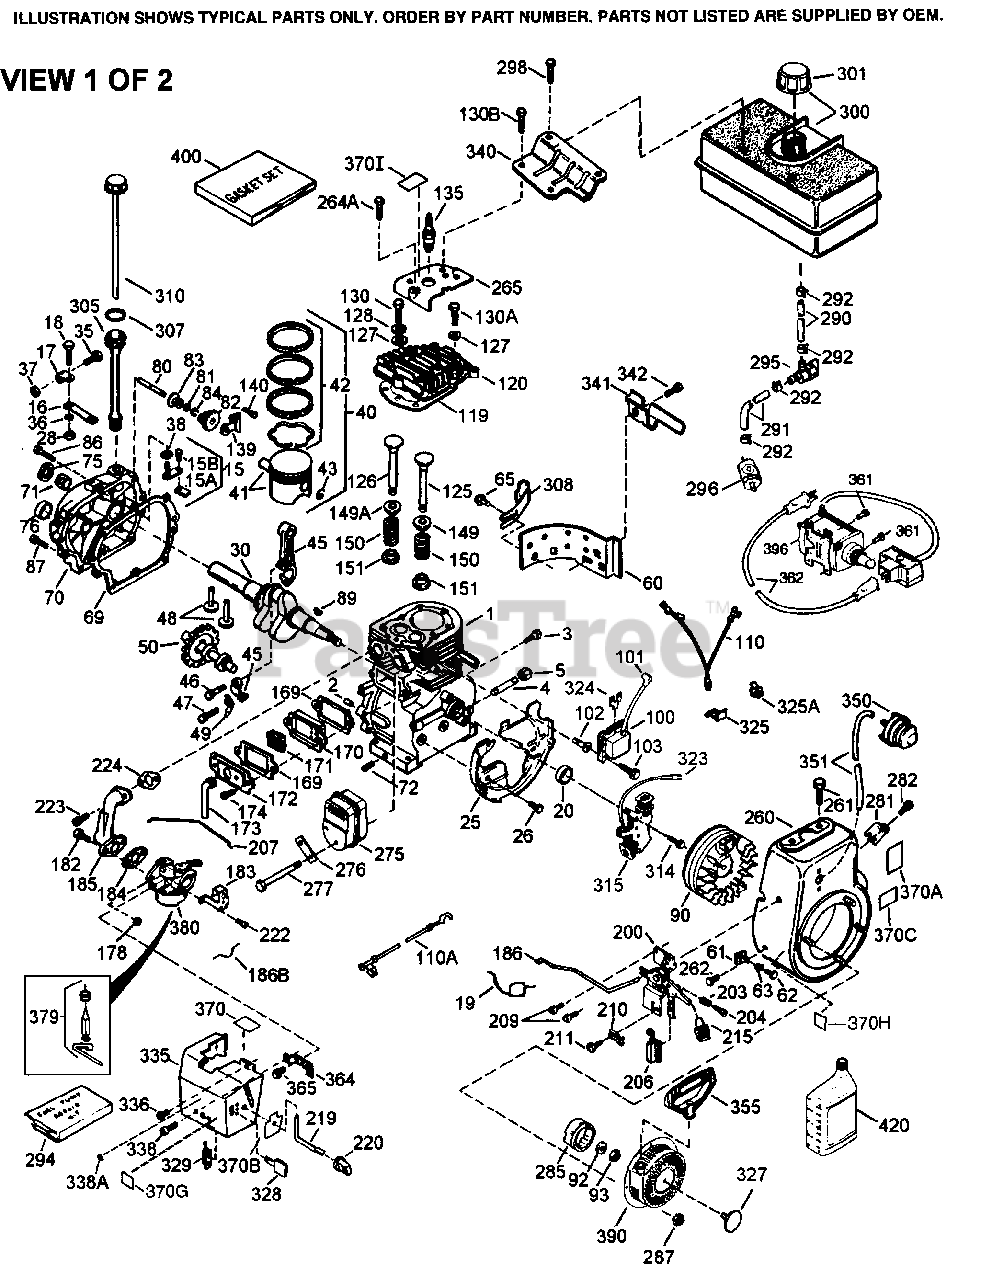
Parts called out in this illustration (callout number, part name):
1	"Cylinder (Cast Iron Liner)(3-5/16") I ncl. 2, 20, 72, 72A & 72B
2	Dowel Pin
3	Screw, 1/4-20 x 1/2"
4	Oil Drain Extension
5	Extension Cap
15	Governor Rod (Incl. 15A & 15B)
15A	Governor Yoke
15B	Screw, 6-40 x 5/16"
16	Governor Lever
17	Governor Lever Clamp
18	Screw, Torx T-15, 8-32 x 3/8"
19	Speed Control Spring
20	Oil Seal
25	Blower Housing Baffle
26	Screw, 1/4-20 x 5/8"
28	Lock Nut, 8-32
30	Crankshaft
35	Screw, 10-32 x 3/4"
36	Lock Washer #8
37	Lock Nut, 10-32
38	Retaining Ring
40	Piston, Pin & Ring Set (Std) (Incl. 4 1, 42 & 43)
40	Piston, Pin & Ring Set (.010" OS) (In cl. 41, 42 & 43)
40	Piston, Pin & Ring Set (.020" OS) (In cl. 41, 42 & 43)
41	Piston & Pin Assembly (Std) (Incl. 43 )
41	Piston & Pin Ass'y. (.010" OS) (Incl. 43)
41	Piston & Pin Ass'y. (.020" OS) (Incl. 43)
42	Ring Set (Std.) (3-5/16")
42	Ring Set (.010" OS)
42	Ring Set (.020" OS)
43	Piston Pin Retaining Ring
45	Connecting Rod Ass'y. (Incl. 47 & 49)
47	Connecting Rod Bolt
48	Valve Lifter
49	Oil Dipper
50	Camshaft (MCR)
60	Blower Housing Extension
62	Screw, 8-32 x 3/8"
69	* Cylinder Cover Gasket
70	Cylinder Cover (Incl. 71, 75 & 80)
71	Crankshaft Bushing
80	Governor Shaft
82	Governor Gear Ass'y. (Incl. 81)
83	Governor Spool
84	Retaining Ring
86	Screw, 1/4-20 x 1-3/16"
87	Screw, 1/4-20 x 1-11/16"
89	Flywheel Key
90	Flywheel (W/Ring Gear)
92	Lock Washer
93	Flywheel Nut
100	Solid State Ignition
101	Spark Plug Cover
102	Soild State Mounting Stud
103	Screw, Torx T-15, 10-24 x 15/16"
110	Ground Wire
110A	Ground Wire (10.50" with male & femal e flag terminals)
119	* Cylinder Head Gasket
120	Cylinder Head
125	Exhaust Valve (Std.)(Incl. 151)
125	Exhaust Valve (1/32" OS) (Incl. 151)
126	Intake Valve (Std.) (Incl. 151)
126	Intake Valve (1/32" OS) (Incl. 151)
128	Belleville Washer
130	Screw, 5/16-18 x 1-1/2"
130A	Screw, 5/16-18 x 1-3/4"
130C	Screw, 5/16-18 x 2"
130C	Screw, 5/16-18 x 5/8"
135	Resistor Spark Plug (RJ19LM) also ava ilable in Packaged Part #740081
139	Governor Gear Bracket
140	Screw, 10-24 x 1/2"
149	Valve Spring Cap
149A	Valve Spring Cap
150	Valve Spring
151	Valve Spring Keeper
169	* Valve Cover Gasket
170	Breather Body
171	Breather Element
172	Valve Cover
173	Breather Tube
174	Screw, 10-24 x 1/2"
178	Nut & Lock Washer 1/4-28
182	Screw, 1/4-28 x 1"
183	Choke Bracket
184	* Carburetor To Intake Pipe Gasket
185	Intake Pipe
186	Governor Link
186B	Choke Spring
200	Control Bracket (Incl.19,203,204,206)
203	Compression Spring
204	Screw, Torx T-10, 5-40 x 7/16"
206	Terminal
207	Throttle Link
215	Control Knob
219	Choke Rod
220	Control Knob
222	Screw, 10-32 x 1/2"
223	Screw, Torx T-30, 5/16-18 x 1-1/8"
224	* Intake Pipe Gasket
260	Blower Housing
261	Screw, 5/16-18 x 3/4"
262	Screw, T-40, 5/16-24 x 21/32"
264A	Screw, 1/4-20 x 5/8"
265	Cylinder Head Cover (Black)
275	Muffler
276	Locking Plate
277	Screw, 5/16-18 x 4-3/16"
281	Starter Bubble Cover
285	Starter Cup
290	Fuel Line
292	Fuel Line Clamp
298	Screw, 1/4-15 x 3/4"
300	Fuel Tank (Incl. 292 & 301)
301	Fuel Cap (Red)
305	Oil Fill Tube
307	"O" Ring
308	Fill Tube Clip
310	Dipstick
314	Screw, 1/4-20 x 3/4"
315	Alternator Coil (18 Watt) (Incl. 323)
323	Terminal
325	Wire Clip
328	Ignition Key (also available in Packa ged Part #740077)
335	Carburetor Cover
336	Screw, 10-32 x 1/2"
338	Screw, 10-32 x 3/8"
338	Screw, 10-32 x 1/2"
340	Fuel Tank Bracket
341	Fuel Tank Bracket
343	Key Switch Bracket
350	Primer Assembly (also available in Pa ckaged Part #740101)
351	Primer Line
355	Starter Handle (Mitten Grip) also ava ilable in Packaged Part #740053B
364	Carburetor Cover Bracket
365	Screw, 8-32 x 27/64"
370	Decal - Speed Control & Choke
370	Decal - Primer - International Symbol
370	-1
370	Decal - Tecumseh Logo for Top of Reco il Starter
370I	Warning Decal (Bilingual)
380	Carburetor (Incl. 184)
390	Rewind Starter Note: This engine cou ld hav e been built with 590733 start er.
396	Electric Starter Motor (Optional)
400	* Gasket Set (Incl. items marked PK in notes) Incl. part #'s 27272A (1), 278 96A (2),27915A (1),29673 (1),29673 (1 ),33263 (1),33629 (1),34698A (1) 3526 2A (1),35317 (1),36451 (1)
900	Replacement Engine None.
900	Replacement Short Block 756336, order from 71-999.
999	Winter Maintenance Kit incl. 5W30 Oil , Spark Plug, Key, & Ultra-Fresh
999	Winter Maintenance Kit (incl. 0W30 Sy nthetic Oil, Spark Plug, Key, & Ultra -Fresh)
